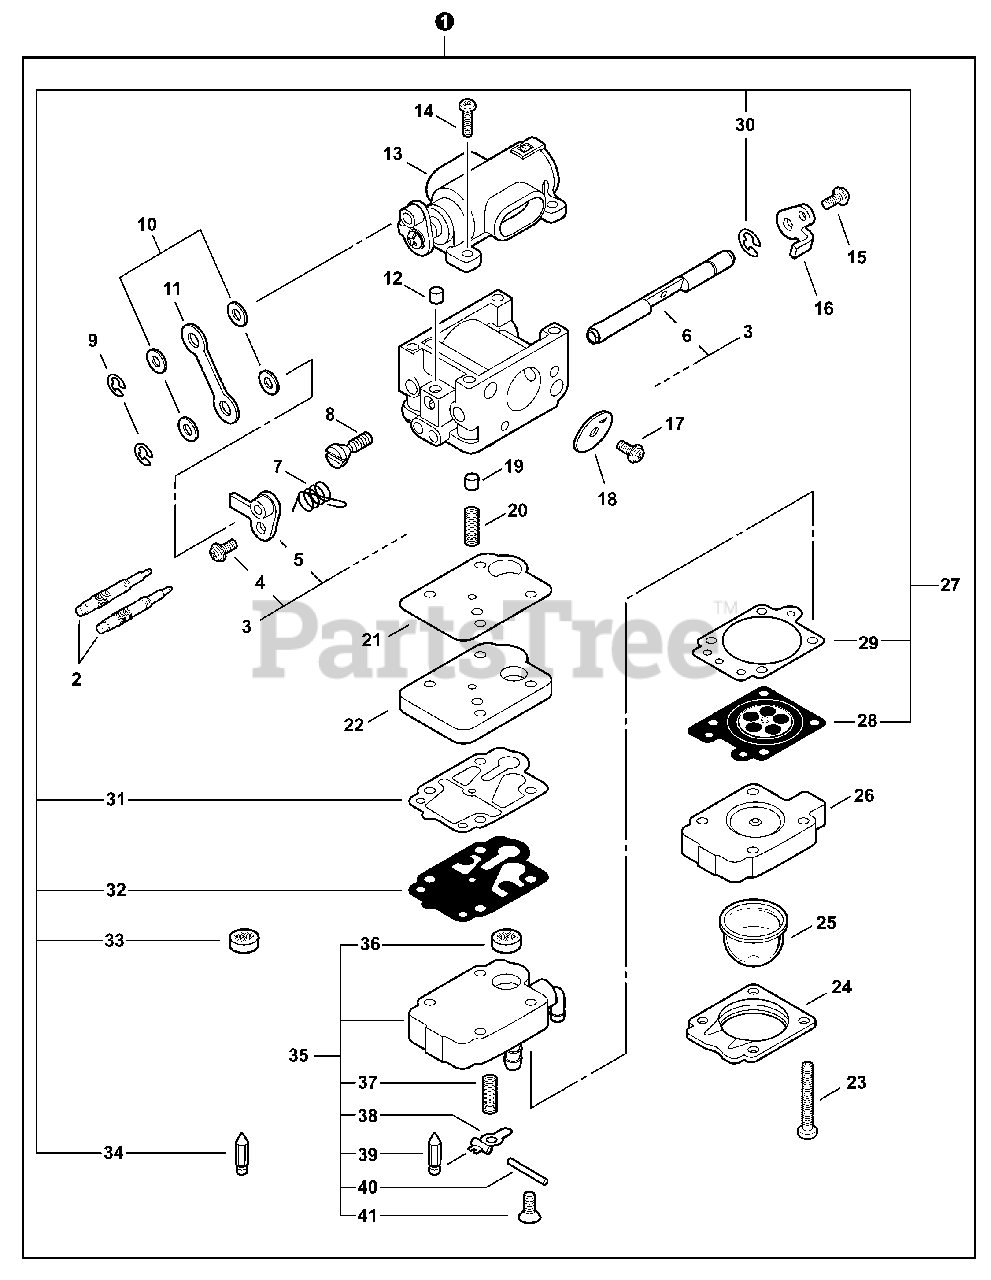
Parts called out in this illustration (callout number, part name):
1	CARBURETOR WLA-1
2	NEEDLE - MIXTURE
3	THROTTLE SHAFT ASSY
5	LINK, THROTTLE
6	SHAFT, THROTTLE
8	SCREW, IDLE ADJUST
9	RING, RETAINING
13	AIR VALVE ASSY
16	LEVER, CHOKE
18	VALVE, THROTTLE
19	PISTON ASSY
21	GASKET, PASSAGE
22	PLATE, PASSAGE
23	SCREW, IDLE ADJUST
24	RETAINER, PURGE BULB
25	BULB, PURGE
26	PURGE BASE ASSY
27	REPAIR KIT
28	DIAPHRAGM, METERING
29	GASKET, METERING
30	RING, RETAINING
31	GASKET, PUMP
32	DIAPHRAGM, PUMP
33	STRAINER
34	VALVE, INLET NEEDLE
35	PURGE BASE ASSY
36	STRAINER
37	SPRING, METERING LEVER
38	LEVER, METERING
39	VALVE, INLET NEEDLE
40	PIN, METERING LEVER
41	SCREW, METERING LEVER PIN
